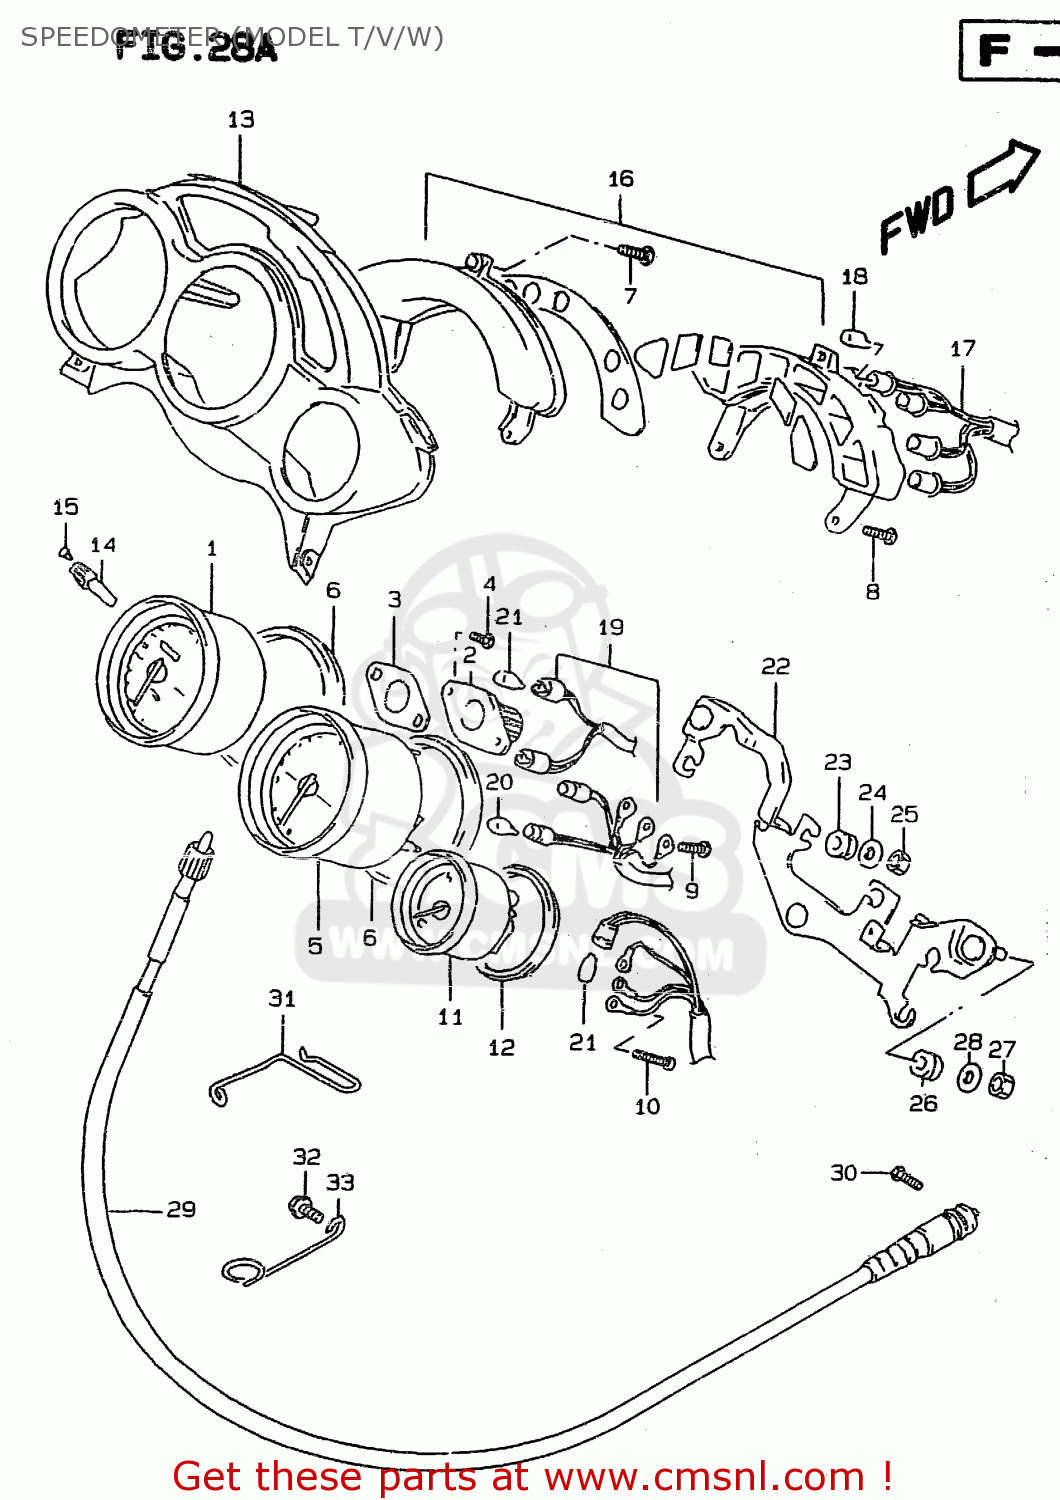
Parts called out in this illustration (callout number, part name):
1	SPEEDOMETER
2	GEAR BOX
3	GASKET,METER GEAR BOX (NAS)
4	SCREW
5	TACHOMETER
6	CUSHION,METER
7	SCREW
8	SCREW
9	SCREW
10	SCREW(3X22)
11	TEMP METER
12	CUSHION,TEMP METER
13	VISOR
14	KNOB,TRIP METER
15	SCREW(2X6)
16	BOX ASSY,PILOT
17	CORD ASSY,PILOT BOX
18	BULB(12V3.4W,T10,BF175-01450A)
19	CORD ASSY
20	BULB(12V1.7W,WB372,T7)
21	BULB(12V1.7W,T6.5)
22	BRACKET,METER
23	CUSHION,METER
24	WASHER(4.3X14X0.8)
25	NUT
26	CUSHION
27	NUT
28	WASHER(6.5X18X1)
29	CABLE ASSY,SPEEDOMETER
30	SCREW
31	GUIDE,SPEEDOMETER CABLE
32	BOLT
33	GUIDE,SPEEDOMETER CABLE NO.3
